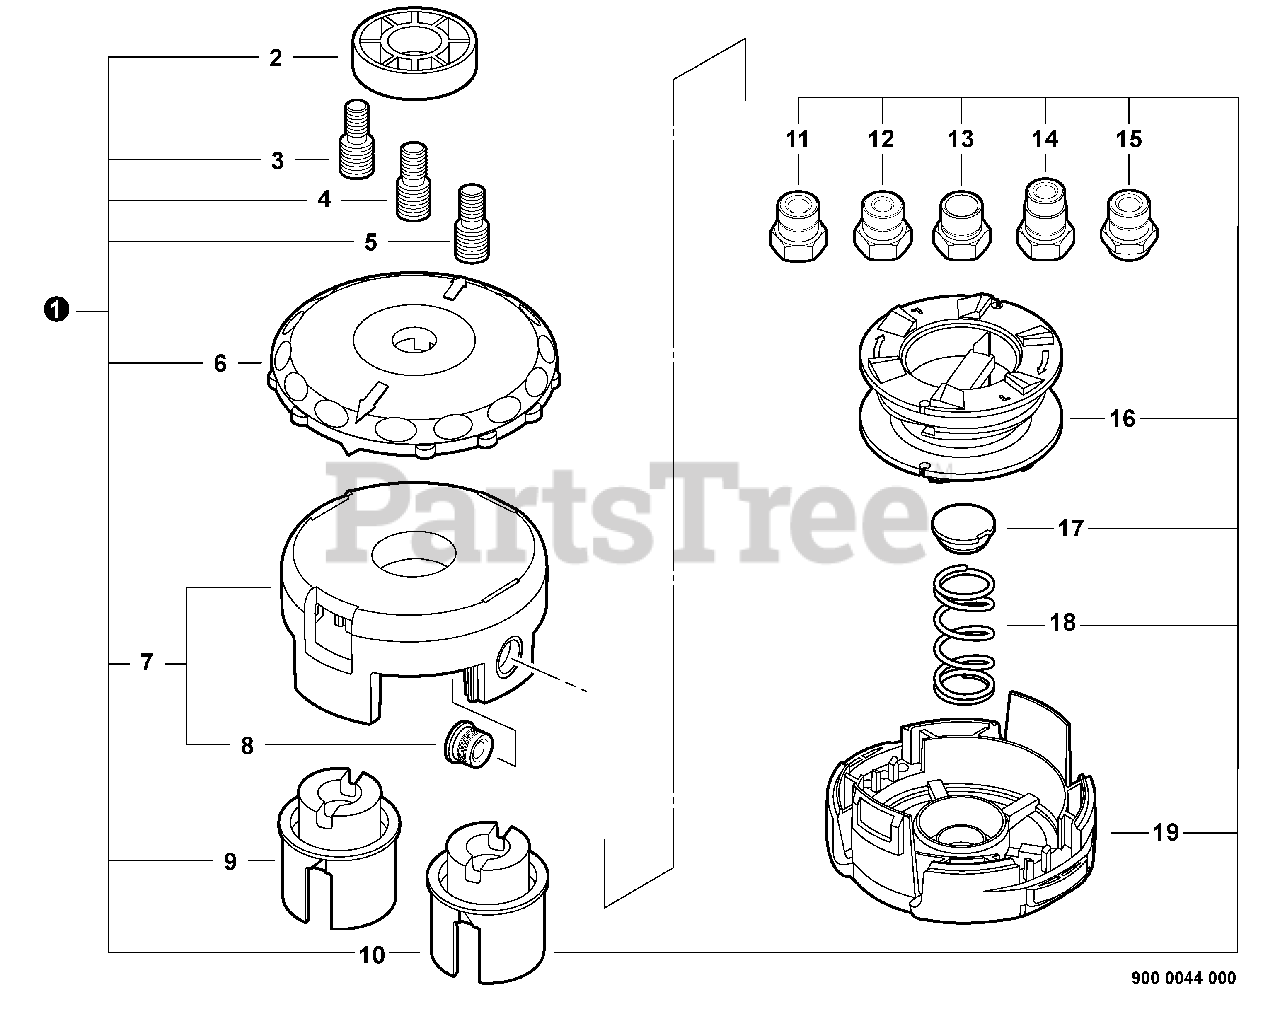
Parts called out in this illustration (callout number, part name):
1	SPEED-FEED 400 TRIMMER HEAD
3	STUD - GOLD -- LEFT HAND
4	STUD - SILVER -- LEFT HAND
5	STUD - BLACK -- RIGHT HAND
7	SPOOL COVER ASSY
9	HUB - BLACK -- LEFT HAND
10	HUB - WHITE -- RIGHT HAND
11	ARBOR - GOLD -- LEFT HAND
12	ARBOR - RED -- LEFT HAND
13	ARBOR - GREEN -- LEFT HAND
14	ARBOR - SILVER -- LEFT HAND
15	ARBOR - BLACK -- RIGHT HAND
17	RETAINER, SPRING
